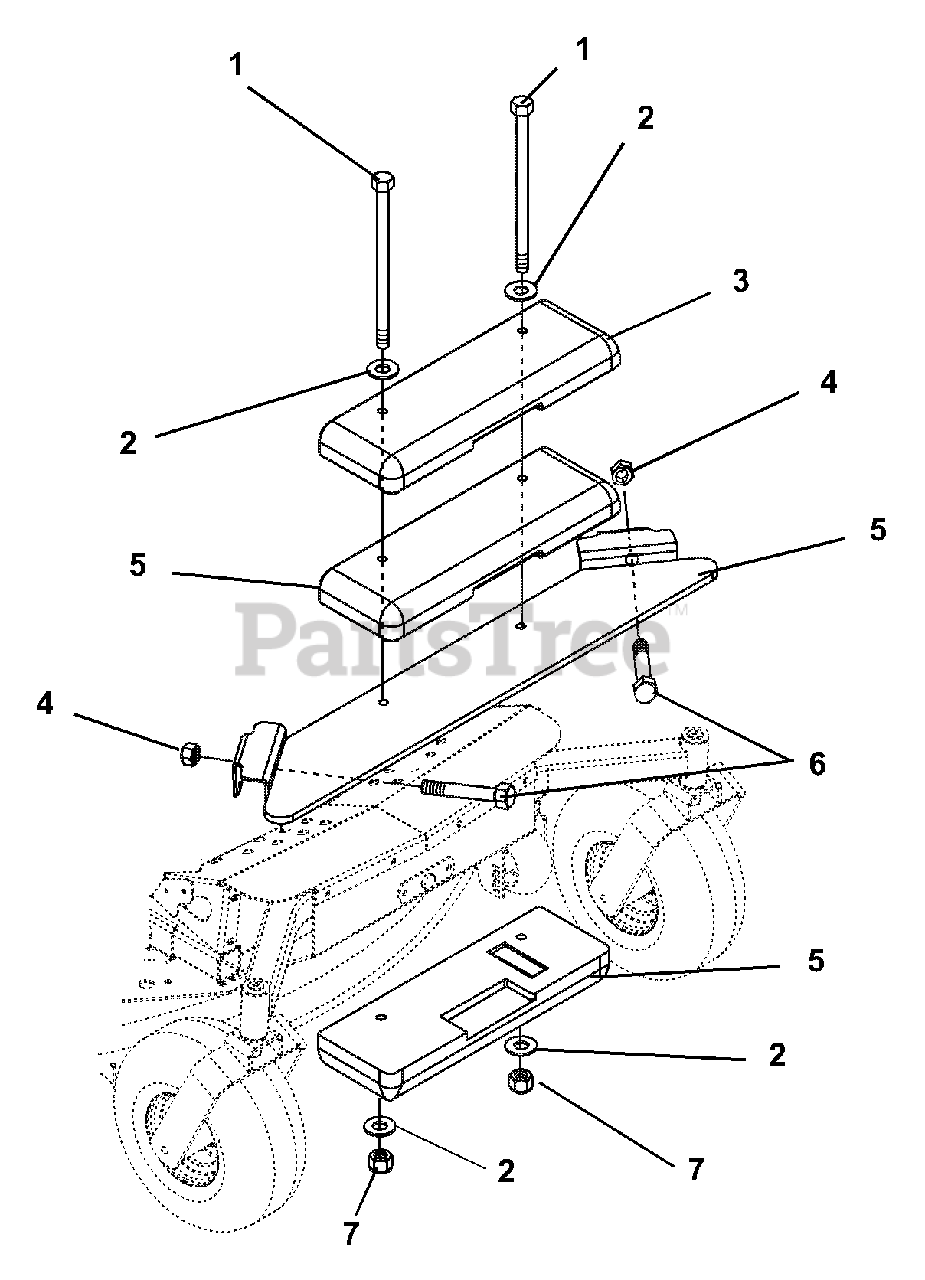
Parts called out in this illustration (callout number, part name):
1	Bolt-Hex .50-13 x 7.50 Grade 5
2	Washer-Flat-Steel .51 x 1.00 x .062
3	Counterweight
4	Nut-Locking .38-16
5	Weldment, Weight Plate
6	Bolt-Hex .38-16 x 3.00 Grade 5
7	Nut-Locking-Center .50-13
